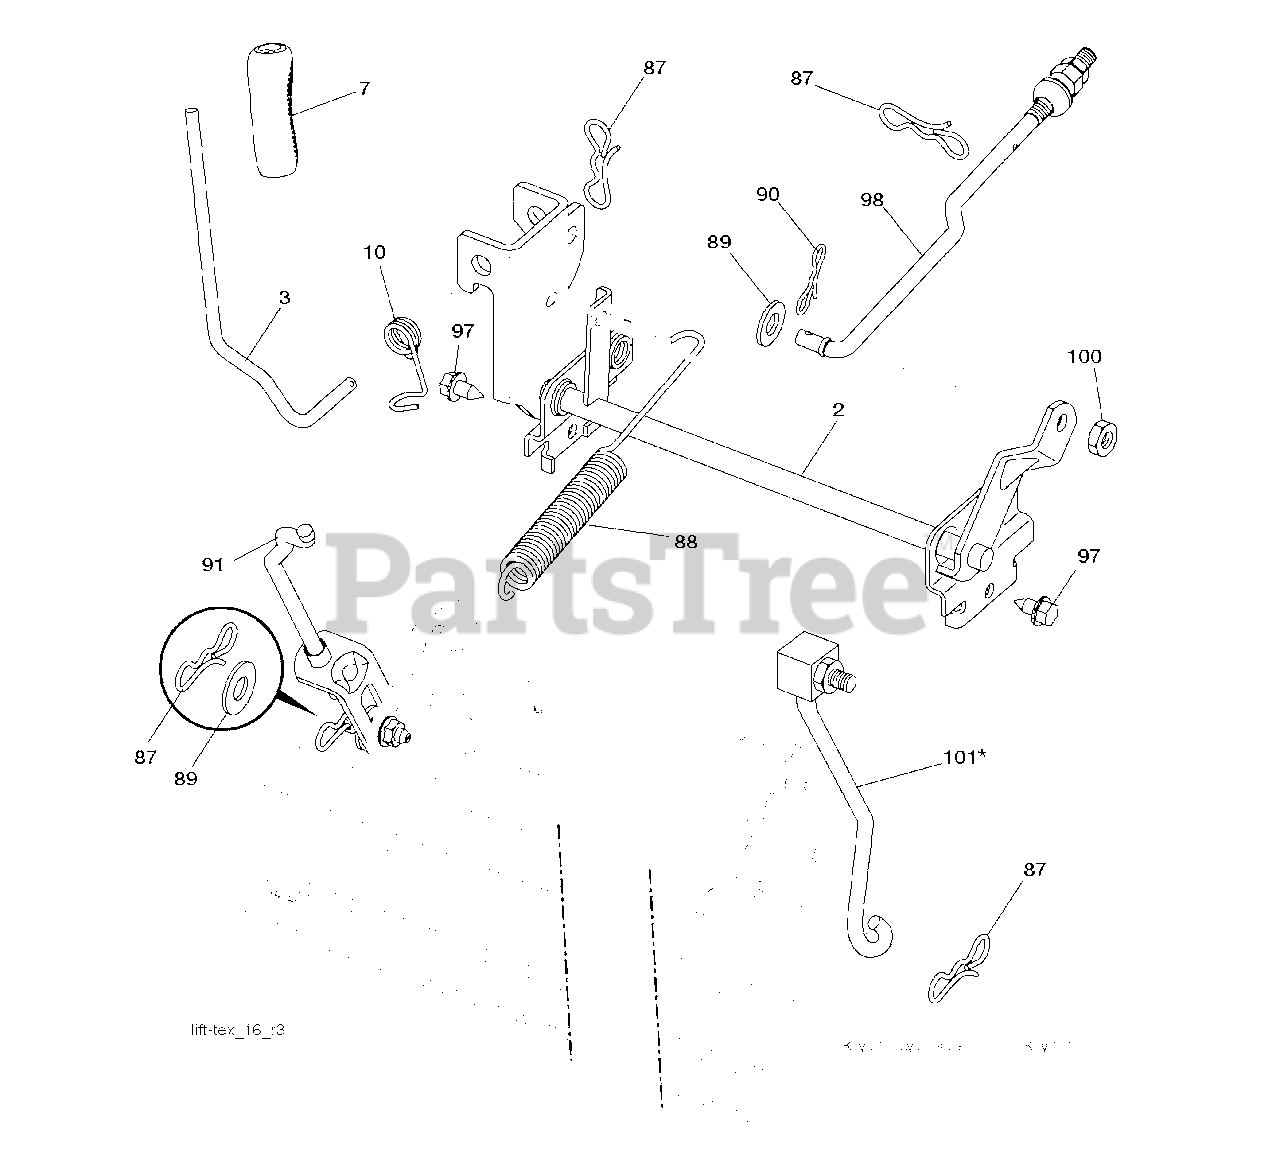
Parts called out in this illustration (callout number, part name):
2	SHAFT.ASM.LIFT.CROSS.H
3	LEVER.LIFT.HANDLE.LT
7	GRIP.HANDLE.LIFT.PVC.BLACK
10	SPRING.TORSION.LIFT.HANDLE
87	PIN.COTTER.7/16.BOW TI
88	SPRING.LIFT.ASSIST
89	WASHER.CLEAR.ZINC
90	PIN.COTTER.5/16.BOW TI
91	LINK.ASM.LIFT.REAR
97	SCREW, 3/8-16X3/4
98	LINK.ASM.SUSP.FRONT.MW
100	LOCKNUT
101	LINK.ASM.LIFT.FIXE.38/42/46"
